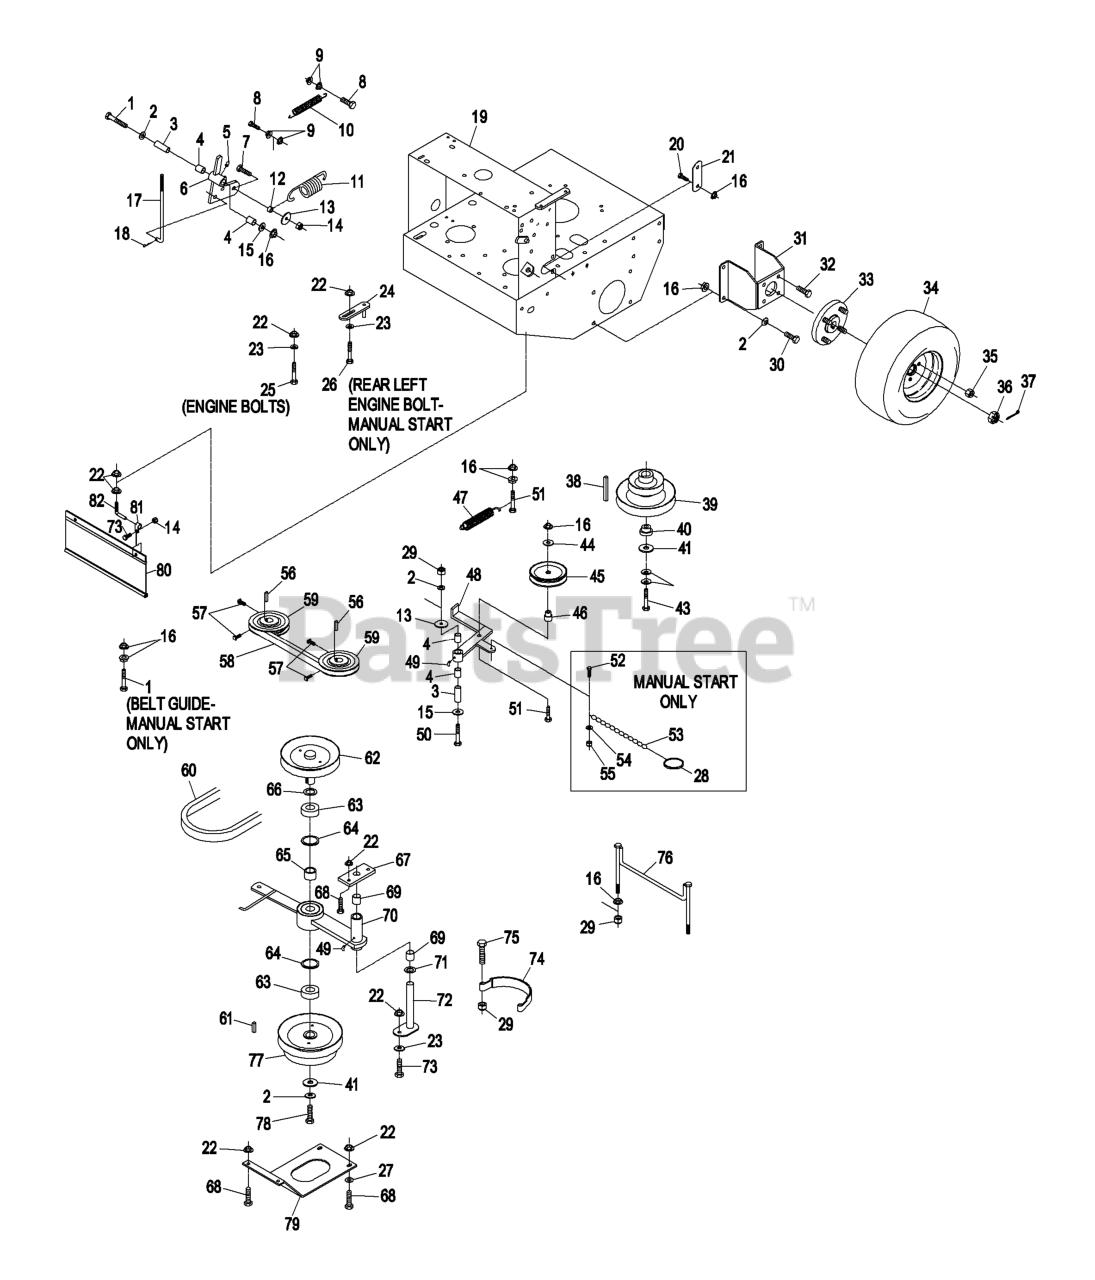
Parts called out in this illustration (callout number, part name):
1	SCREW-HH
2	WASHER-BELLEVILLE
3	BUSHING
4	SLEEVE-BEARING
5	FITTING-GREASE
7	SCREW-HH
8	SCREW-HH
10	SPRING,EXTENSION
11	SPRING,BELT TENSION
12	SPACER,CLUTCH ANCHOR
14	NUT-LOCK, NI
15	WASHER-FLAT
16	NUT-HHF, WHIZ
17	LINKAGE,LOWER
18	PIN-COTTER
20	SCREW-HH
21	ARM-LIFT, DECK
23	WASHER-SPRING
24	GUIDE-BELT
25	SCREW-HH
26	SCREW-HH
27	WASHER-FLAT
28	RING-SPLIT
29	NUT-LOCK, NI
30	SCREW-HH
31	WLD,MOTOR MOUNT 36
32	SCREW-HHF
34	WHEEL AND TIRE ASM
35	NUT-LUG
36	NUT-HEX, SLOTTED
37	PIN-COTTER
38	KEY,MACH 1/4X1/4X2-5/8
39	SHEAVE,DRIVE
40	BUSHING,CLUTCH KEEPER
42	WASHER-SPRING
43	SCREW-HH
44	WASHER-FLAT
46	BUSHING-IDLER
47	SPRING-EXTENSION
48	Idler Arm Weldmt
49	FITTING-GREASE
50	SCREW-HH
51	SCREW-HH
52	SCREW-HSH
53	CHAIN-LINK, TWIST
54	WASHER-FLAT
55	NUT-LOCK, NI
57	SCREW-SET
59	SHEAVE ASM
60	BELT,BLADE CLUTCH
62	SHEAVE,6.13 W/SHAFT
63	BEARING,CLUTCH SHAFT
64	RING-SNAP
65	SPACER,CLUTCH BEARING
66	WASHER-SPACER
67	PLATE-CLUTCH PIVOT
68	SCREW-HH
69	SLEEVE,BEARING
70	Arm Weldmt, Clutch
71	WASHER-SPACER
72	WLD,PIN PIVOT
73	SCREW-HH
74	BAND,BRAKE BLADE
75	SCREW-HH
76	GUIDE - BELT
77	SHEAVE,6.13 W/HUB
78	SCRW,CAP HH
79	PLATE-GUARD
81	CLIP-LOOM
82	MOUNT,DRAG SHIELD
